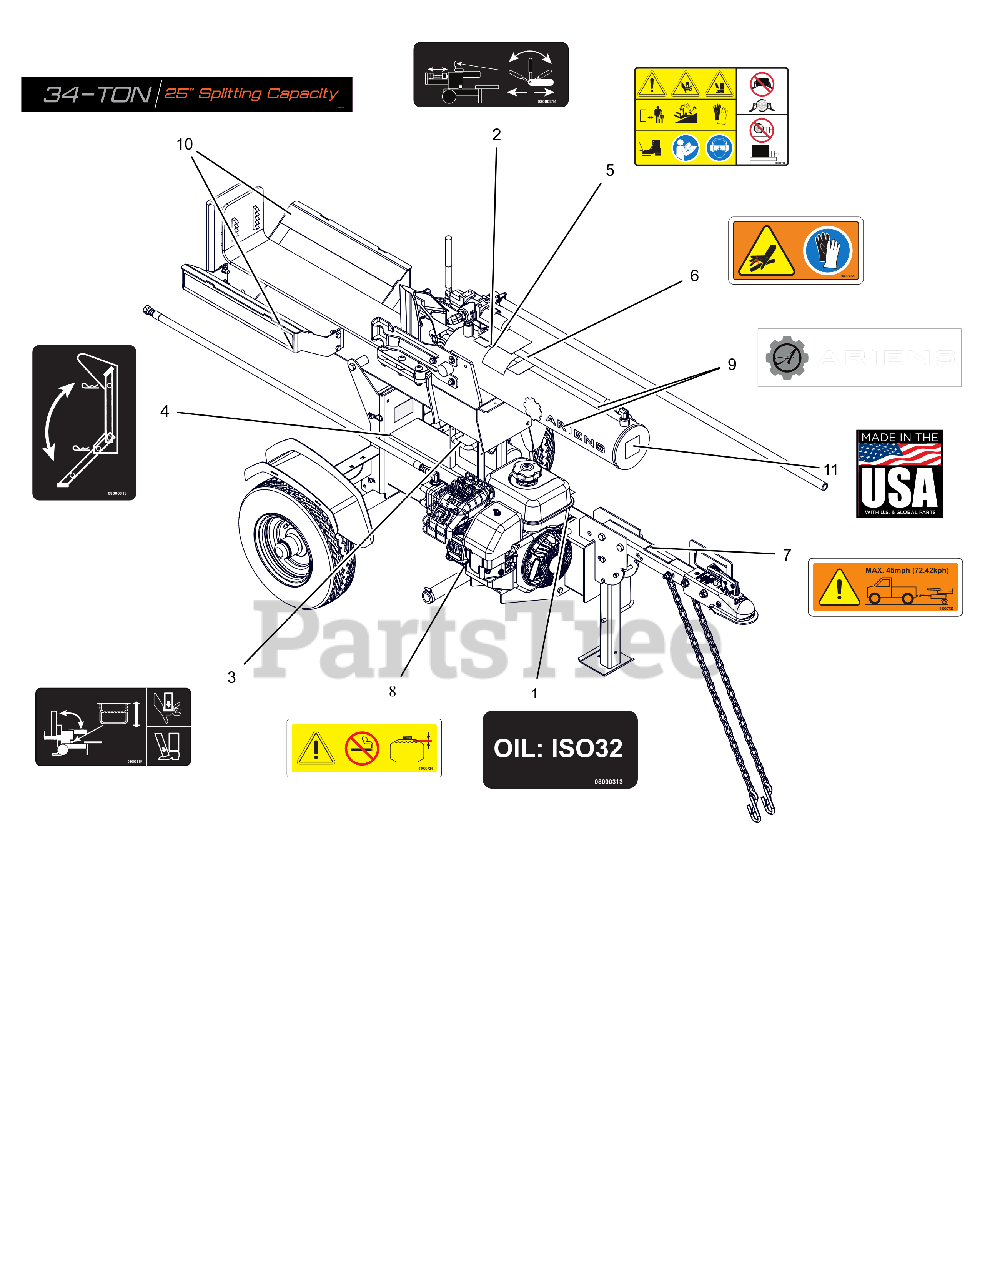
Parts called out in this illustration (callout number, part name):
1	DECAL, LOG SPLITTER-HYD OIL
2	DECAL, LOG SPLITTER-RAM OP
3	DECAL, LOG SPLITTER-TILT OP
4	DECAL, LOG SPLITTER-REAR STAND
5	DECAL,DANGER LOG SPLITTER
6	DECAL,HYD WARNING
7	DECAL,TOWING
8	DECAL,FUEL WARNING
9	DECAL-ARIENS-CYLINDER
10	DECAL-CRADLE-34 TON
11	DECAL, MADE IN USA
